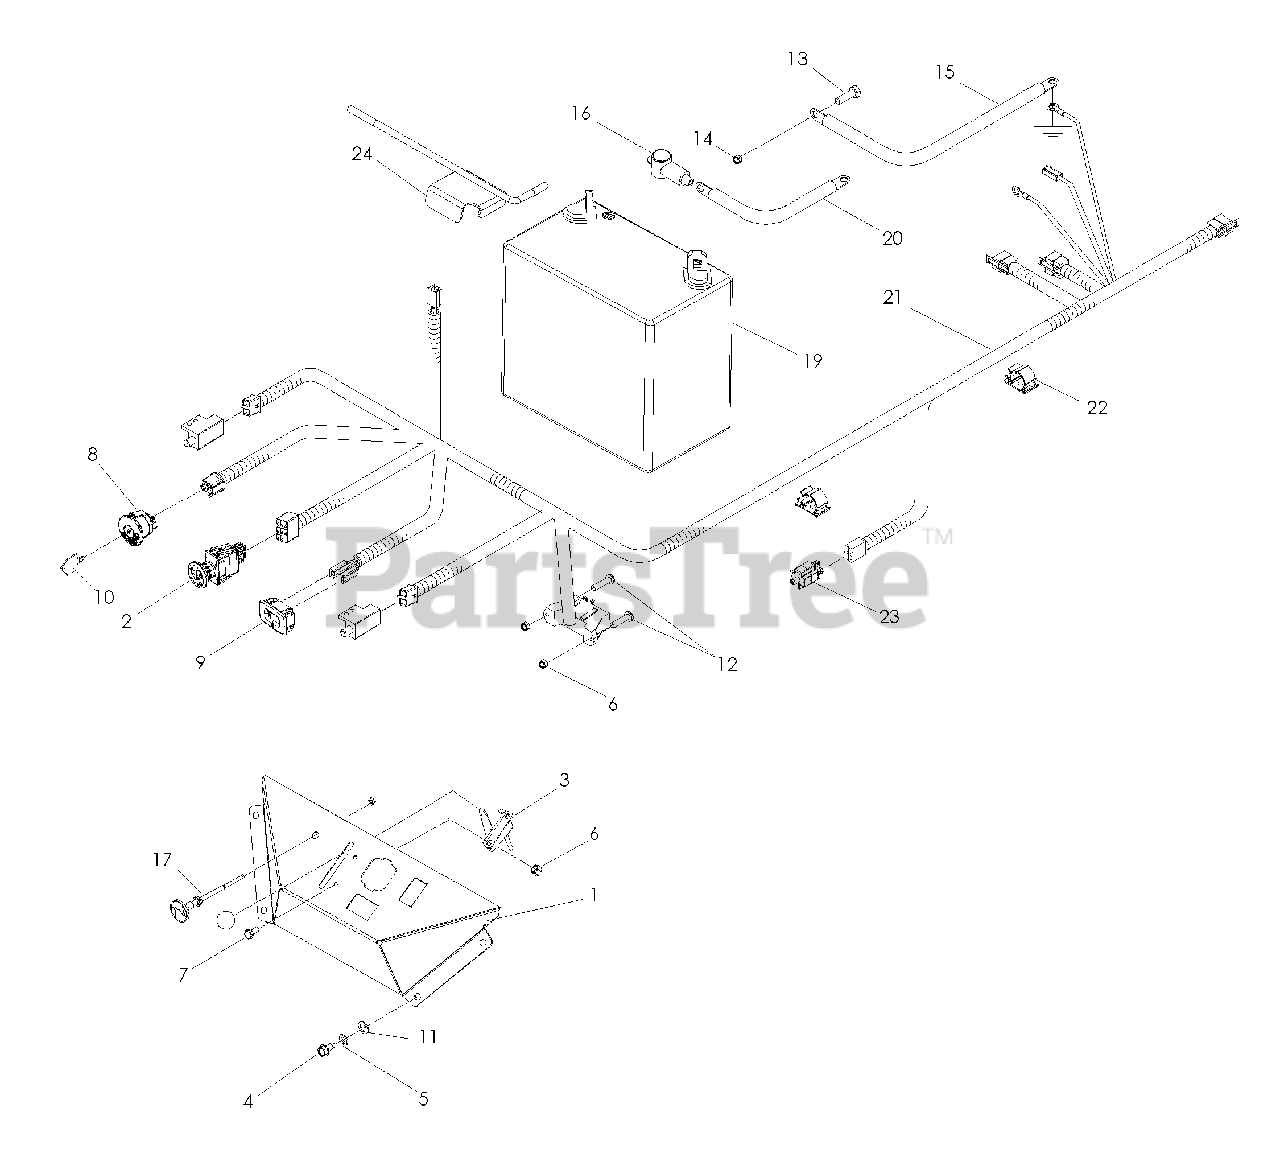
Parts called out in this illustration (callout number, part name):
2	SWITCH, PTO 10 AMP
3	THROTTLE CABLE
4	SCREW 1/4-20 x 5/8
5	WASHER, 1/4 SPLIT LOCK
6	NUT #10-24 HEX NYLOC
7	HCS #10-24 x 1/2
8	SWITCH, IGNITION
9	HOUR METER
10	KEY, IGNITION
11	WASHER, 1/4 FLAT
12	SCREW #10-24 x 7/8 SLT HD
13	HCS 5/16-18 x 3/4
14	NUT 5/16-18 HEX NYLOC
15	CABLE, NEGATIVE
16	INSULATOR-BATTERY
17	CHOKE CNTRL MODEL iZ5225XPBF, iZ5223 IZ6125, iZ25
18	CHOKE CNTRL MODEL iZ4821BF
18	CHOKE CNTRL MODEL iZ4217C, iZ4217 iZ4819, IZ4821, iZ5223VAN
20	BATTERY, DRY
21	CABLE, POSITIVE
23	CLIP, WIRE
24	SWITCH, BRAKE
25	HOLD DOWN, BATTERY
